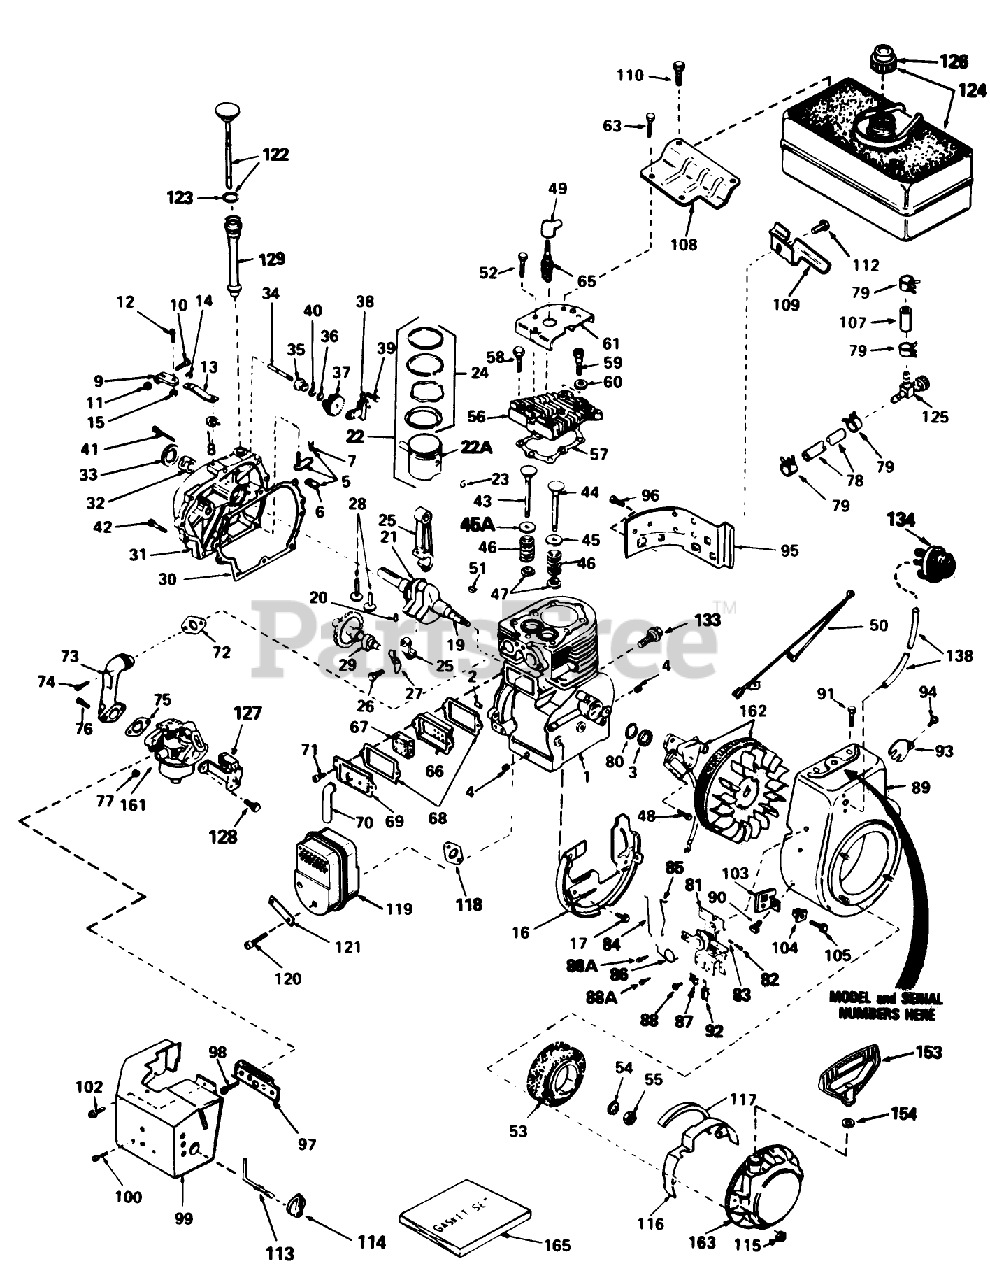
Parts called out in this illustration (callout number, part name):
1	Cylinder Assembly (Incl.Ref. #2, 3, 4 45A)
2	Pin-Dowel
3	Oil Seal
4	Plug-Drain, Oil (SQH 1/4-18)
5	Rod, Governor (Incl. Nos.62 63)
6	Yoke-Governor
7	Screw (6-40x5/16)
8	Ring-Retaining
9	Clamp-Lever, Governor
10	Screw
11	Nut-Lock
12	Screw
13	Lever-Governor
14	Washer-Lock
15	Nut-Lock
16	Baffle Blower Housing
17	Screw (1/4-20x19/32)
19	Crankshaft Assy. (Incl. Nos. 20 21)
20	Pin, Groove
21	Gear, Crankshaft
22	Piston, Pin Ring Assy.(Std.) (Incl. Ref. #24A, 25 26)
22	Piston, Pin Ring Assy. (.010 oversize) (Incl. Ref. #24A, 25 26)
22	Piston, Pin Ring Assy. (.020 oversize) (Incl. Ref. #24A, 25 26)
22A	Piston Pin Assy. (Std.) (Incl. Ref. #26)
22A	Piston Pin Assy. (.010 oversize) (Incl. Ref. #26)
22A	Piston Pin Assy. (.020 oversize) (Incl. Ref. #26)
24	Ring Set (Std.)
24	Ring Set (.010" OS)
24	Ring Set (.020" OS)
25	Rod Assy., Connecting (Incl. Nos. 10 18)
26	Bolt, Connecting Rod
27	Dipper-Oil
28	Lifter-Valve
29	Camshaft (Mech. Comp. Release)
30	Gasket, Cylinder Cover (Incl. Ref. #41)
31	Cover, Cylinder (Incl. Ref. #32, 33 34)
32	Bushing, Crankshaft
33	Seal, Oil
34	Shaft-Governor
35	Spool-Governor
36	Ring-Retaining
37	Governor Gear ASM
38	Bracket-Gear, Governor
39	Screw (10-24x1/2)
40	Washer-Flat
41	Screw (1/4-20x1-3/16)
42	Screw (1/4-20x1-11/16)
43	Valve, Intake (Std.) (Incl. Ref. #58)
43	Valve, Intake (1/32" oversize) (Incl. Ref. #58)
44	Valve, Exhaust (Standard)(Incl. No. 9)
44	Valve, Exhaust (1/32" oversize)(Incl. No. 9)
45	Cap-Spring, Valve
45A	Seal-Intake Valve
46	Spring-Valve
47	Keeper-Spring, Valve
48	Screw
49	Cover-Spark Plug
50	Wire, Ground
51	Key-Flywheel
52	Screw (1/4-20 X 5/8)
53	Hub Screen Assy., Starter
54	Washer-Belleville
56	Head Cylinder
57	Gasket-Cylinder Head
58	Screw (5/16-18x1-1/2)
59	Screw (5/16-18x1-25/32)
60	Washer-Flat
61	Cover, Cylinder Head
63	Screw
65	Plug, Spark (J17LM or equiv.)
65	Plug, Spark (Champion RCJ-8)
66	Body-Breather
67	Element-Breather
68	Gasket-Breather
69	Cover-Valve
70	Tube-Breather
71	Screw
72	Gasket-Intake
73	Pipe-Intake
74	Screw (T-30, 5/16-18x1-3/32)
75	Gasket-Carburetor To Intake Pipe
76	Screw (1/4-28x1)
77	Nut and Lock Washer (1/4-28)
78	Line-Fuel
79	Clamp-Line, Fuel
80	Gasket Stator
81	Control Assy., Remote Speed (Incl. Ref. #90 thru 93)
82	Screw
83	Spring-Compression
84	Link-Governor
85	Link-Throttle
86	Spring-Throttle
87	Conduit
88	Screw (10-32 x 3/8)
88A	Screw (10-32 x 1/2)
89	Housing, Blower
90	Screw, Hex Hd.
91	Screw (5/16-18x3/4)
92	Terminal
93	Screw
94	Screw (8-32 x 3/8)
95	Extension, Blower Housing
96	Screw
97	Bracket-Carburetor
98	Screw (8-32x27/64)
99	Cover-Carburetor
100	Screw (10-32 x 3/8)
102	Screw (10-32x1/2)
103	Bracket
104	Grommet
105	Screw
107	Line-Fuel (8.62)
108	Bracket-Tank, Fuel (Black)
109	Bracket-Tank, Fuel
110	Screw (1/4-15x7/8)
112	Screw (1/4-20x19/32)
113	Rod-Choke
114	Knob-Control
115	Nut and Lock Washer (1/4-28)
116	Guard, Starter
117	Seal, Snowguard
118	Gasket Exhaust
119	Muffler
120	Screw
121	62513 SNWTHWR W/284
122	Dipstick, Oil (Incl. Ref. #88)
123	O-Ring
124	Tank Assy., Fuel (Incl. No. 115)
125	Valve-Shut Off
126	Cap, Fuel
127	Bracket-Choke
128	Screw (10-32 x 1/2)
129	Tube Fill
133	Screw (1/4-20x1/2)
134	Primer Assy.
138	Line-Primer
153	Handle-Starter, Mitten Grip
154	Washer
161	Carburetor (Incl. Ref. #75)
162	Magneto (The complete magneto is not available as an assembly. The magneto number is shown for reference purposes only. Order component parts individually, as shown in parts list.)
163	Starter, Rewind
165	Gasket Set
